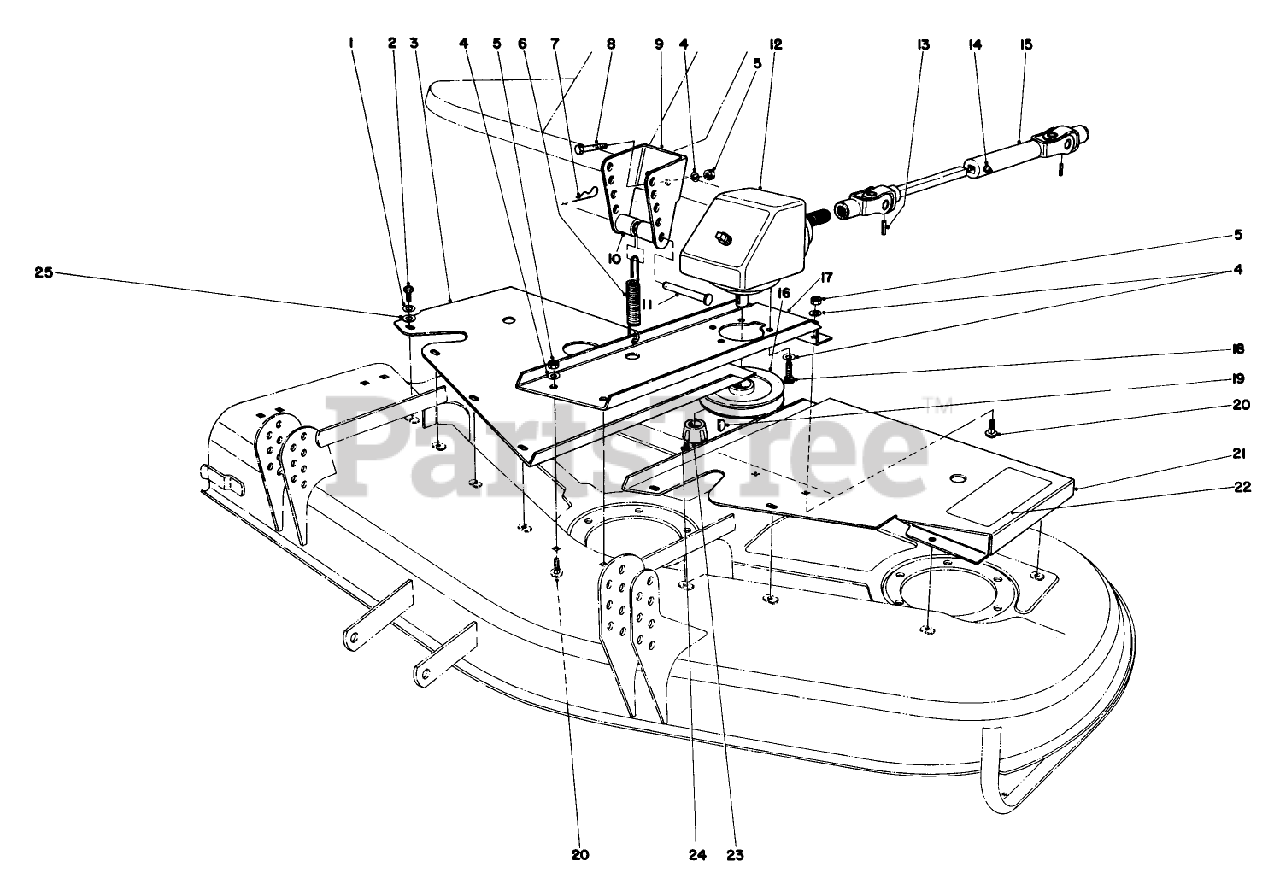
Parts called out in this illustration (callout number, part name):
1	WASHER-LOCK
2	SCREW THD 1/4 20 5/8
3	RH COVER WA R
4	WASHER-LOCK
5	NUT-HEX
6	Extension Spring
7	PIN-HAIR
8	SCREW-HH
9	Bracket-Spring
10	SPACER
11	PIN-CLEVIS
12	GEAR BOX ASM
13	PIN-ROLL
14	FITTING-GREASE
15	UNIVERSAL JOINT
16	PULLEY WA BO
17	Base-Bear Box
18	SCREW-HSH
19	KEY-WOODRUFF
20	SCREW-CARR
21	LH COVER WA R
22	DECAL
23	BUSHING-LOCK, TAPER
24	SCREW-SET, HSH
25	WASHER-FLAT
